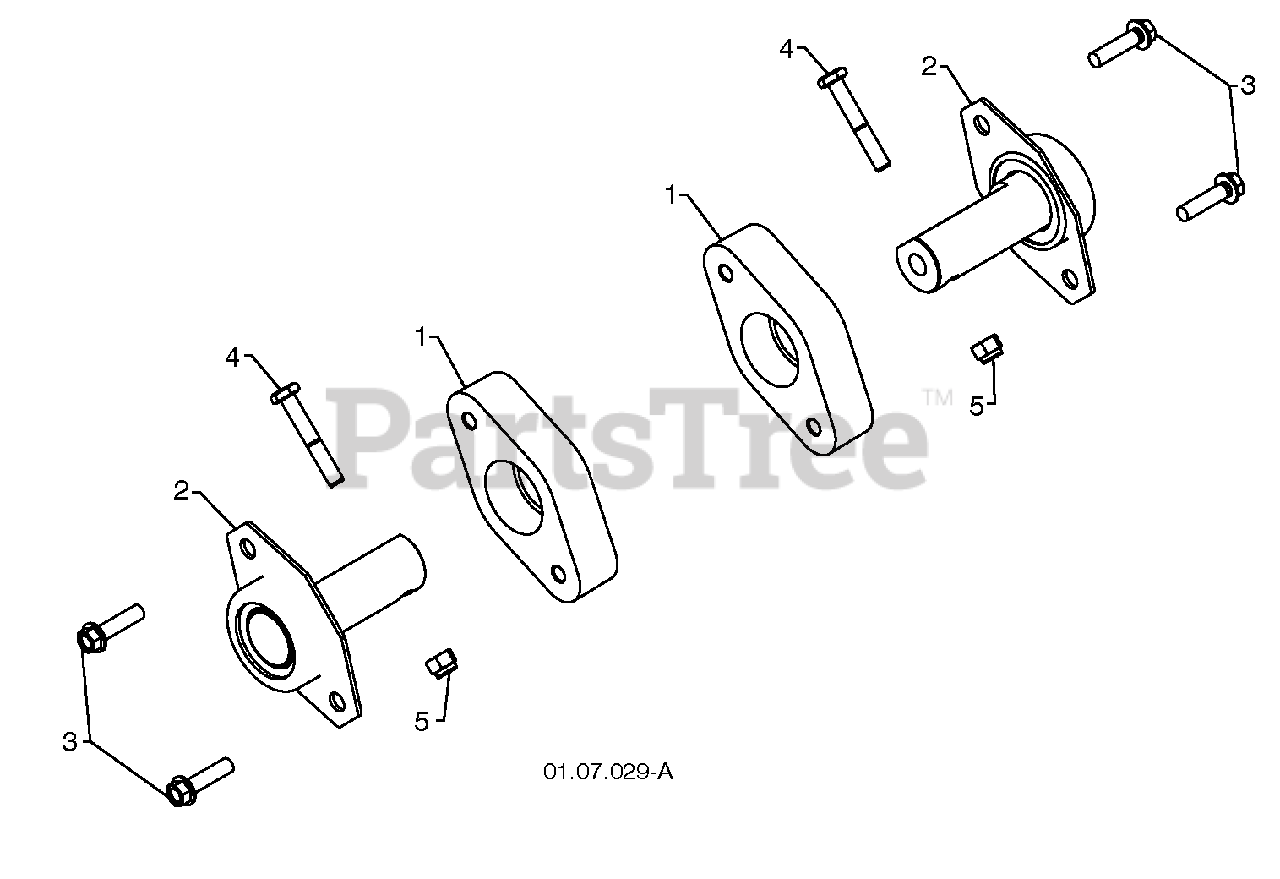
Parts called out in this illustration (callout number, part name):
1	PLASTIC RETAINER
2	AUGER BALL BEARING
3	SCREW 5/16-18 X 1.00 .625
4	SCREW 1/4-20 X .625
5	NUT 1/4-20
